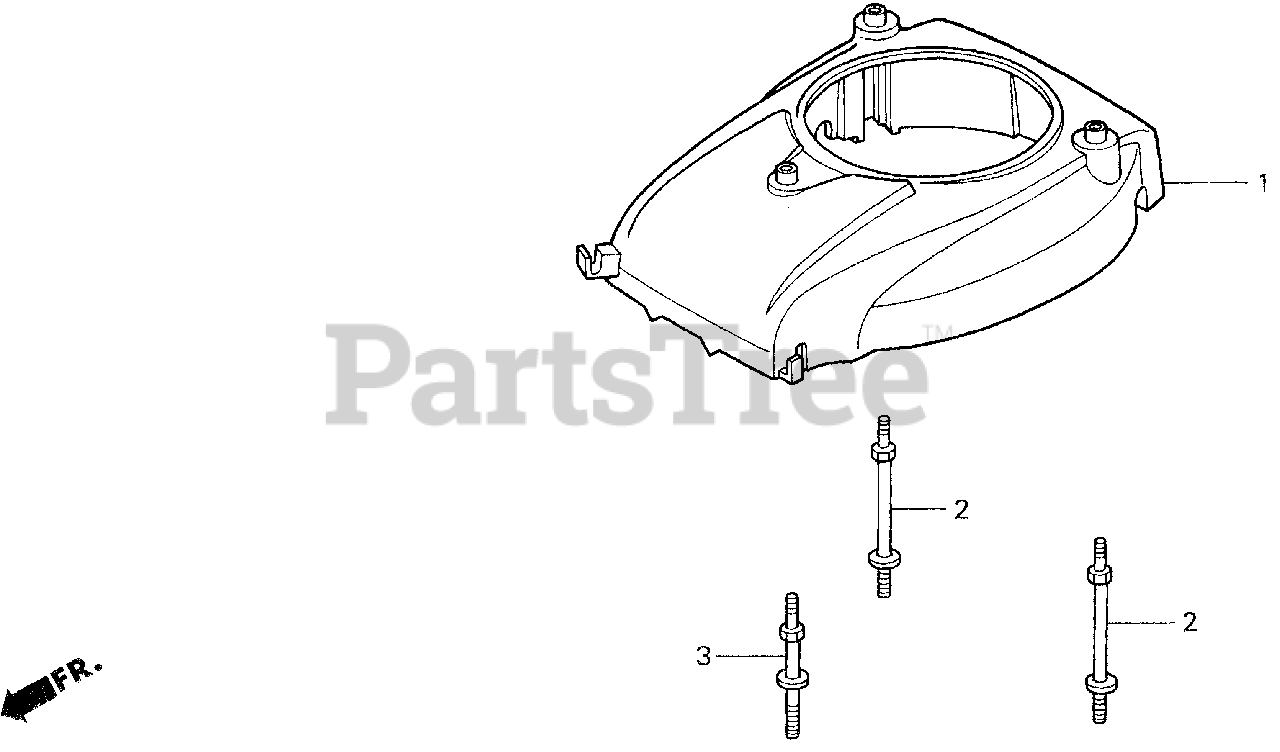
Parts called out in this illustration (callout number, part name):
1	COVER, FAN *R8* (BRIGHT RED)
2	BOLT A, STUD
3	BOLT B, STUD
